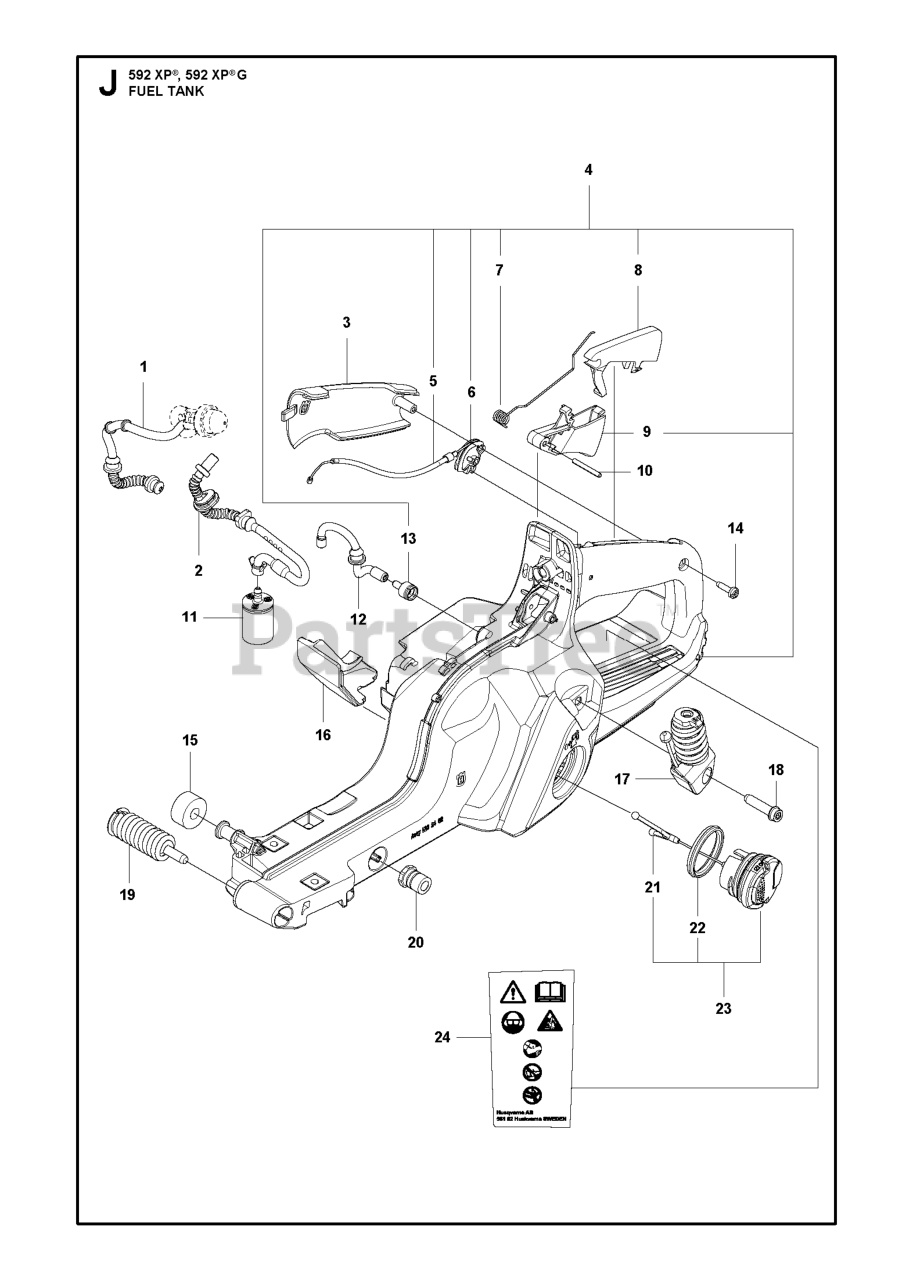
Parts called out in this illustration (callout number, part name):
1	FUEL HOSE PURGE OUT
2	FUEL HOSE ASSY FUEL HOSE ASSY
4	FUEL TANK ASSY 90 CC SPARE PAR
5	THROTTLE CABLE ASSY
8	THROTTLE LOCK
9	THROTTLE TRIGGER
10	PIN 3X25
11	FUEL FILTER
12	FUEL HOSE FUEL TANK VENTILATI
14	SCREW CITXPANT
15	DEFLECTION LIMITER
16	WEAR PROTECTION
17	ANTIVIBRATION ELEMENT REAR
19	ANTIVIBRATION ELEMENT FRONT
20	LATERAL SUPPORT
23	TANK CAP ASSY
